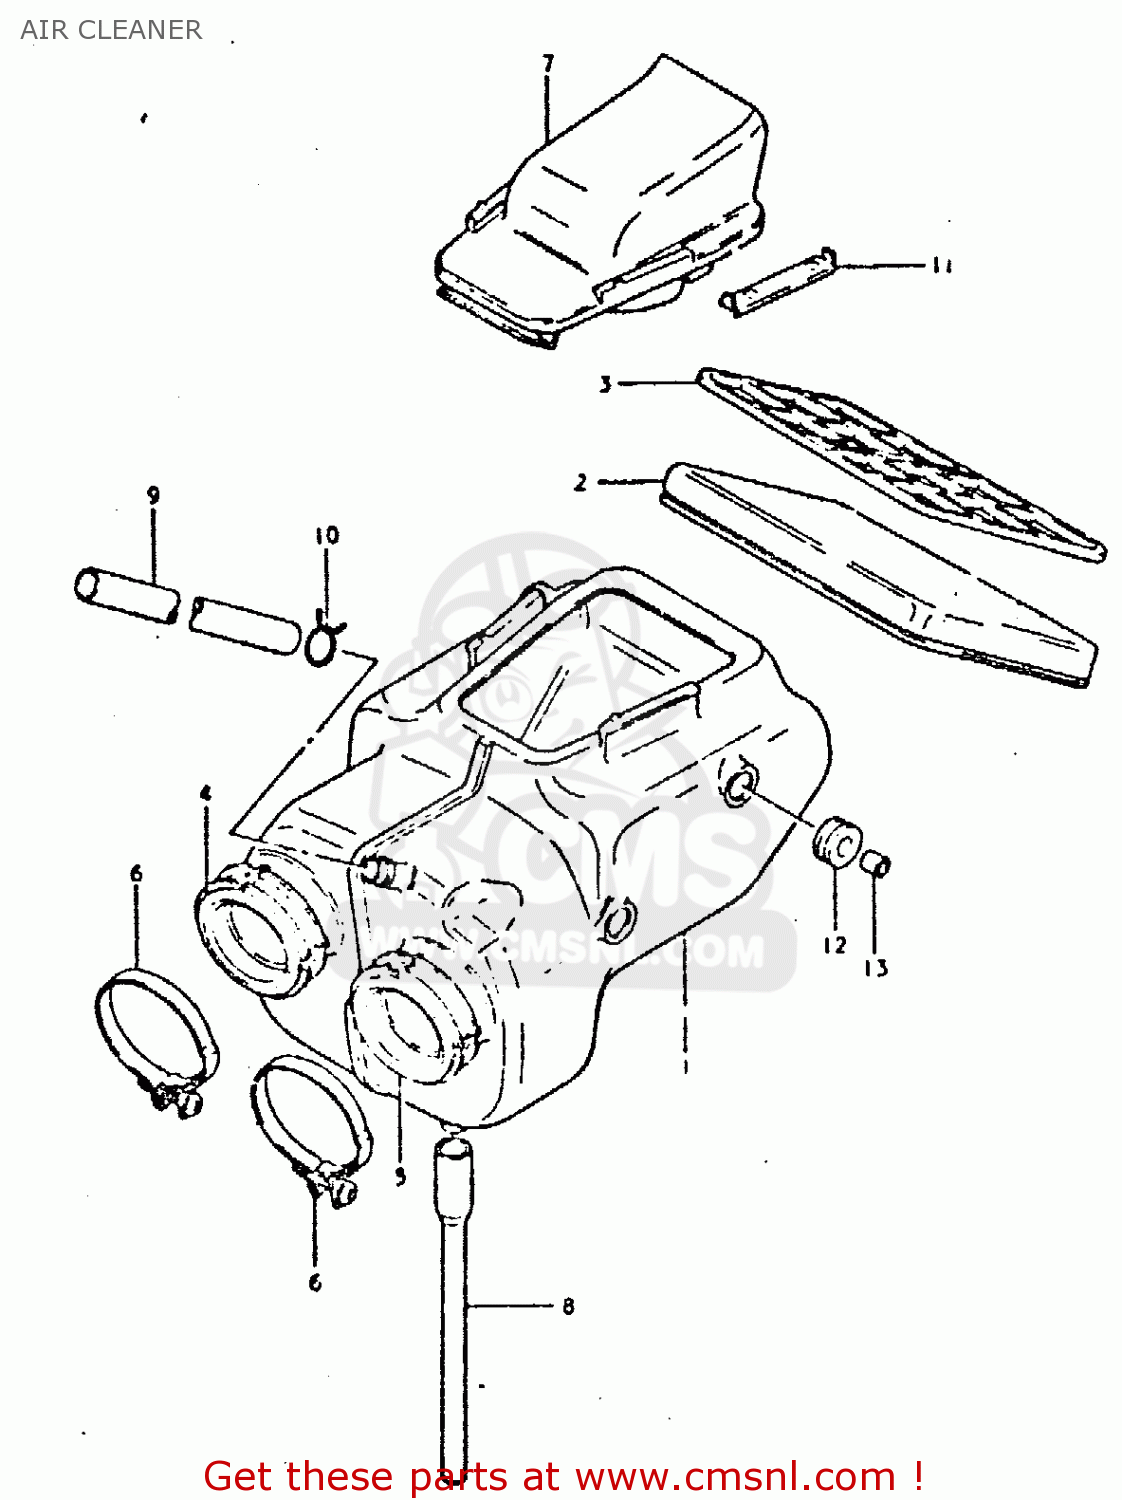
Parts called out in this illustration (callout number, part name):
1	CLEANER ASSEMBLY,AIR
2	FILTER
3	HOLDER NO.2
4	OUTLET,R
5	OUTLET,L
6	CLAMP
7	CAP
8	DRAIN TUBE
9	TUBE,BREATHER
10	CLAMP
11	SLIDER
12	CUSHION
13	WASHER
